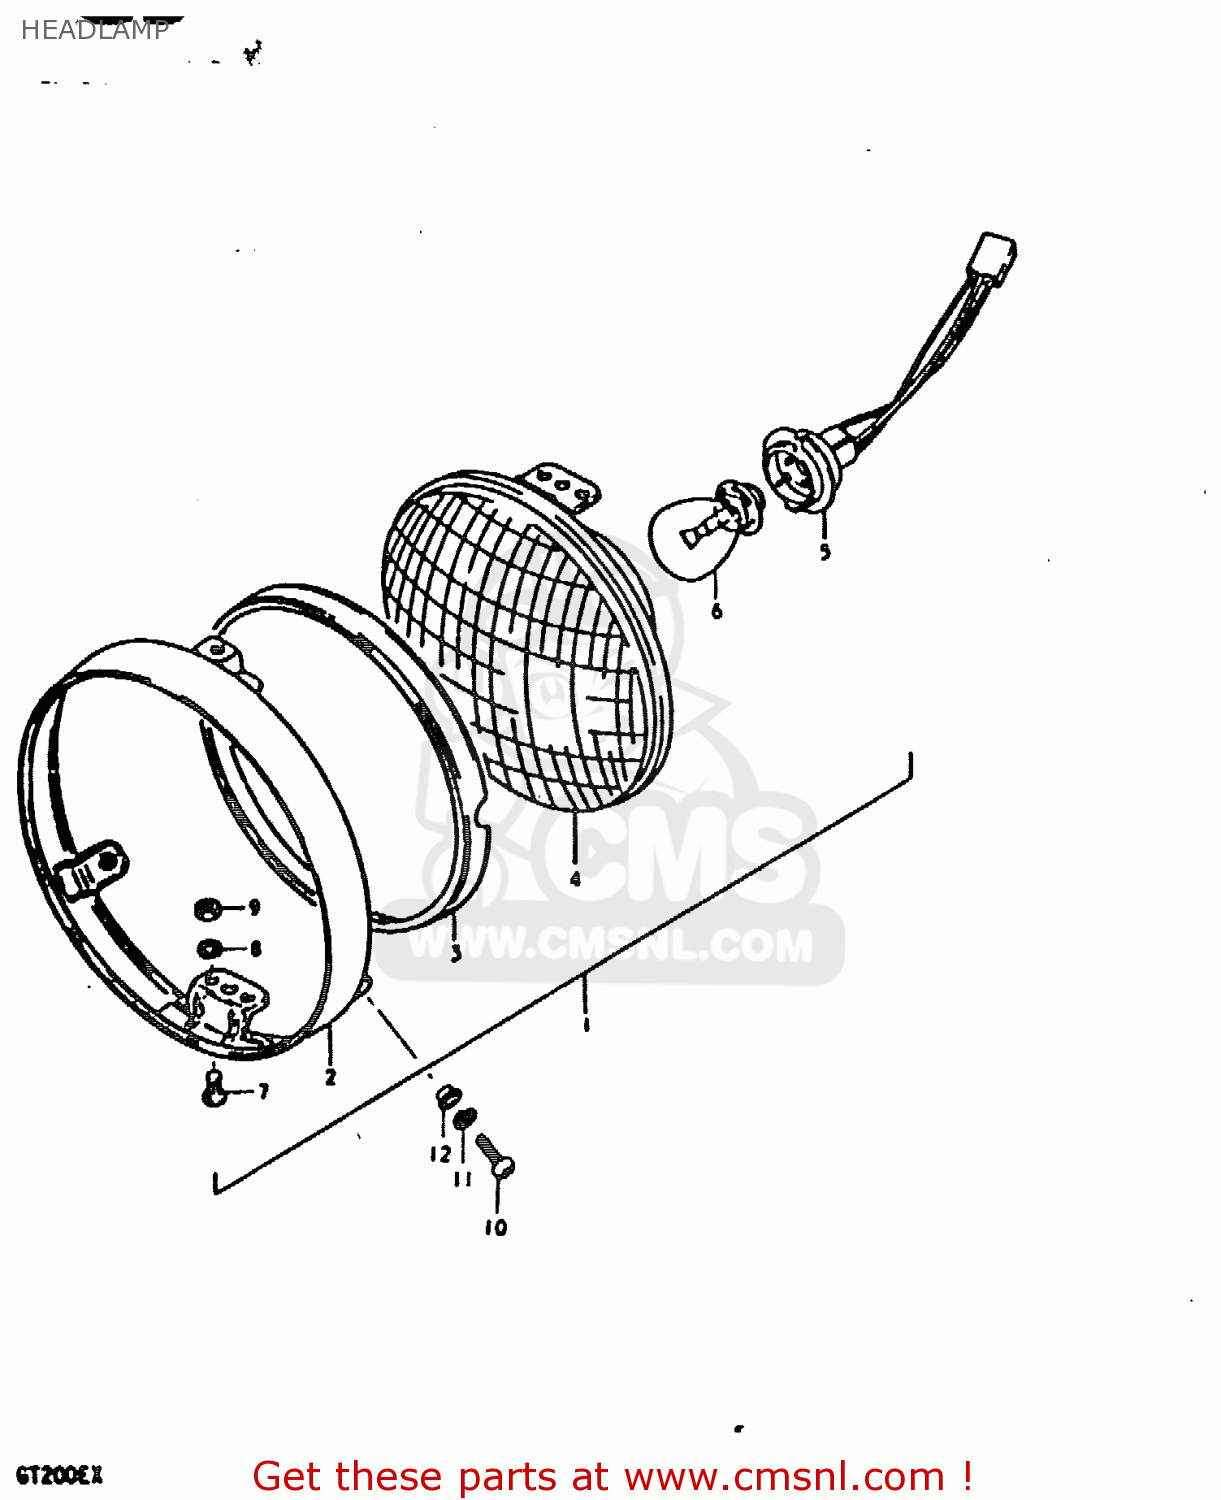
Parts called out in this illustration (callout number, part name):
1	HEADLAMP ASSY
2	RIM
3	RETAINER,HEADLAMP
4	UNIT
5	SOCKET
6	BULB 12V35/35W
7	SCREW
8	LOCK WASHER
9	NUT
10	SCREW
11	WASHER,LOCK
12	WASHER
